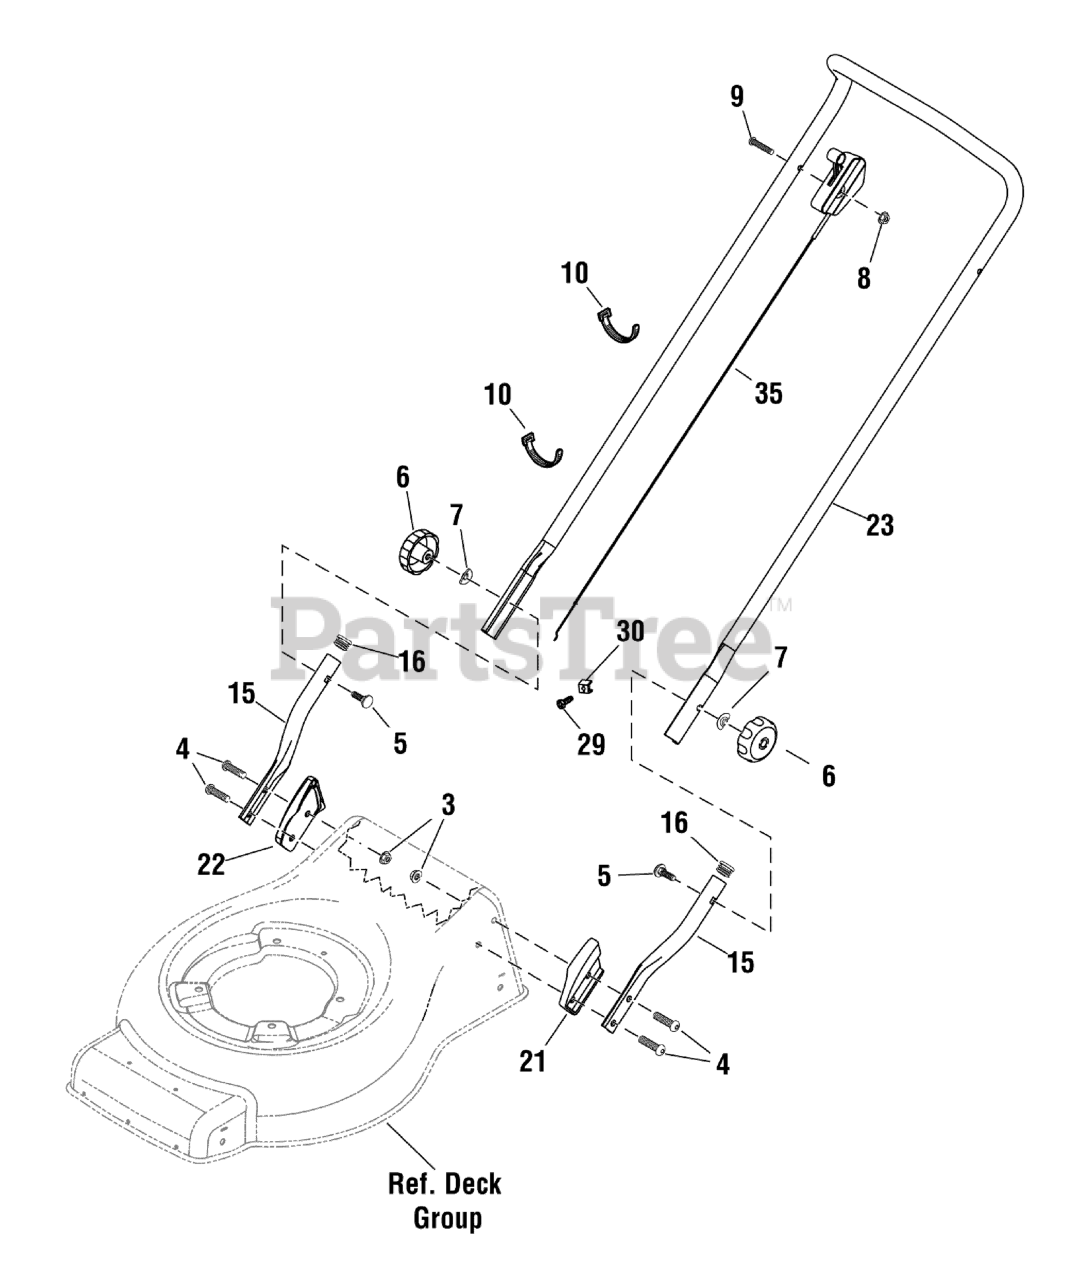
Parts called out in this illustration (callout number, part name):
3	NUT, Lock, Nylon, M8 - 1.25
4	BOLT, Hex Key Head, M8 x 1.25
5	BOLT, Carriage, M8 x 1.25
6	KNOB, M8 x 1.25
7	WASHER, Formed
8	NUT, Hex Lock, M6 x 1
9	SCREW, Button Head, M6 x 1
10	TIE, Cable
15	HANDLE, Lower
16	PLUG, 7/8
21	BRACKET, Handle Mount, LH
22	BRACKET, Handle Mount, RH
23	HANDLE, Upper
30	CLAMP, Cable
35	THROTTLE CABLE ASSEMBLY
